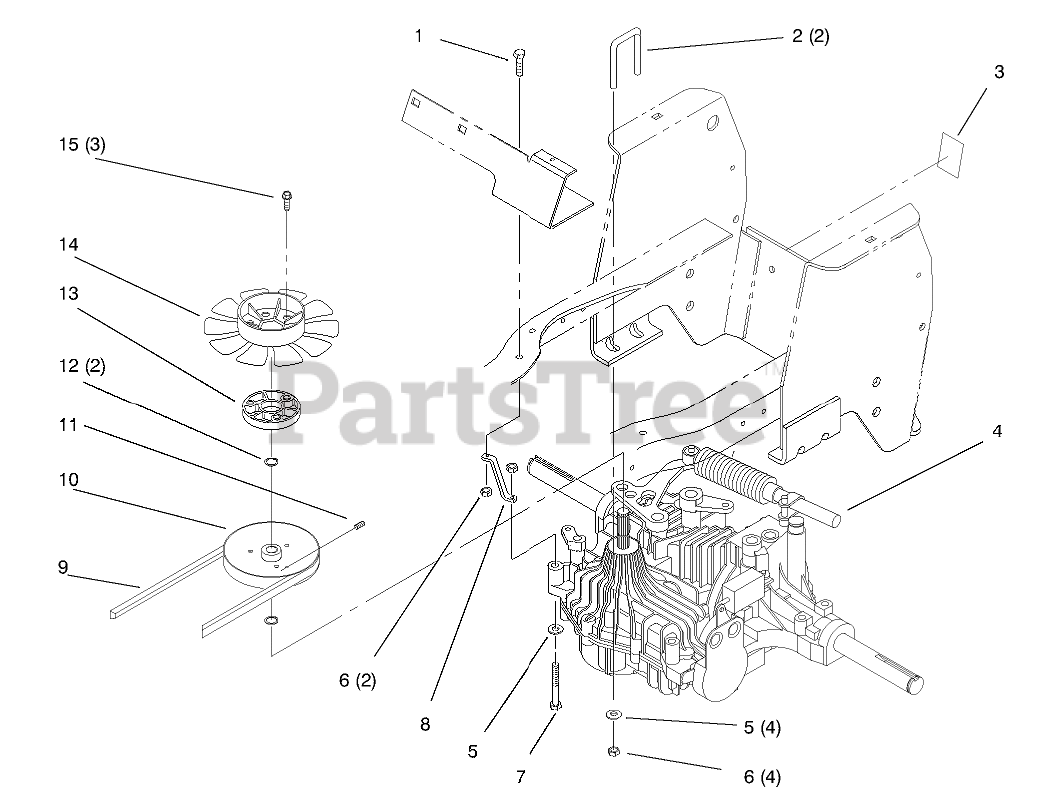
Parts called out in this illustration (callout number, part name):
1	SCREW-HH
2	U-BOLT
3	Decal-Hydro Valve (Only On: 72085)
3	Decal-Bypass (Only On: 72104)
4	TRANSAXLE - HYDROSTATIC
5	WASHER-PLAIN
6	NUT-LOCK, NI
7	SCREW-HH
8	STRAP-TRQ HY
9	V-BELT, HYDRO
10	PULLEY-HYDRO TRANS
11	SCREW-HSH
12	SNAP RING
13	SPACER - FAN
14	FAN - HYDRO
15	SCREW-HWHTF
